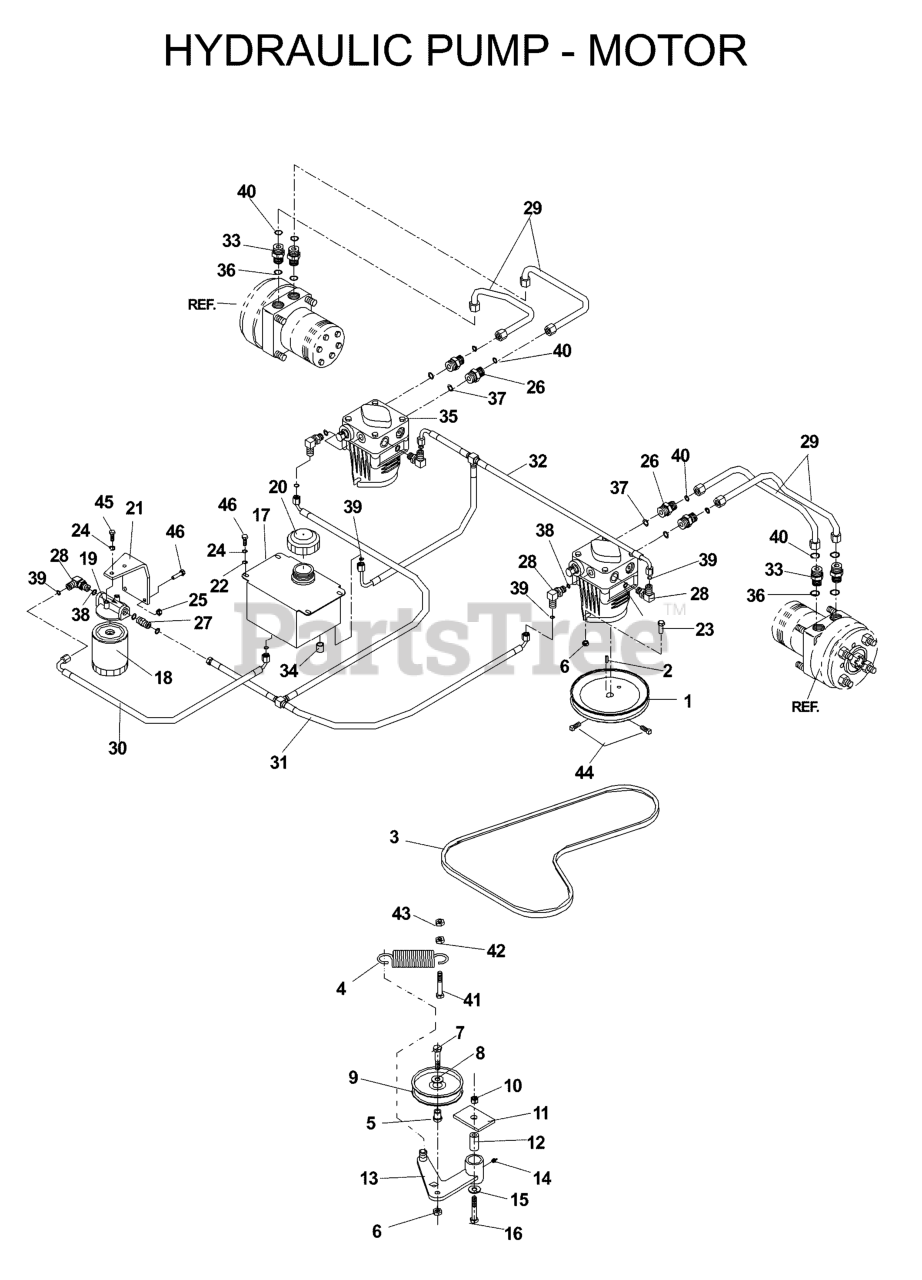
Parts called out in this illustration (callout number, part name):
2	KEY 5 MM SQ X 25 MM
3	PUMP BELT
5	BUSHING, IDLER FLANGE
6	NUT 3/8C CENTERBLOCK
7	HCS 3/8-16 X 1 3/4 GR5
8	WASHER 3/8 FLAT
9	IDLER PULLEY
10	NUT 1/2-13 HEX NYLOC ZD
12	PIVOT BUSHING
13	IDLER ARM WLDT
14	ZERK
15	WASHER 1/2 FLAT
16	HCS 1/2C X 3 1/4
18	HYDRAULIC OIL FILTER
19	FILTER HEAD
20	HYDRAULIC CAP
21	OIL FILTER BRKT
22	WASHER 1/4 FLAT
23	4CS 3/8C X 1 SERRATED HEAD
24	LOCKWASHER 1/4"
25	NUT.1/4-20.HEX.NYLOC.ZD
26	FITTING, STRAIGHT F6400-8-8-0
27	HYDRAULIC FITTING
28	ELBOW, F6801-6-6-0 90 DEGREE
29	HYDRAULIC HOSE
31	T-ASSEMBLY
34	NUT 9/16-18 JIC CAP
35	10CC PUMP W/RTN'S
41	HCS 3/8C X 2
42	NUT 3/8C WHIZ
43	NUT 3/8-16 NYLOC
44	SCREW 5/16C X 5/8 SQ HEAD
45	HCS 1/4C X 5/8
46	HCS 1/4C X 3/4 HCS
